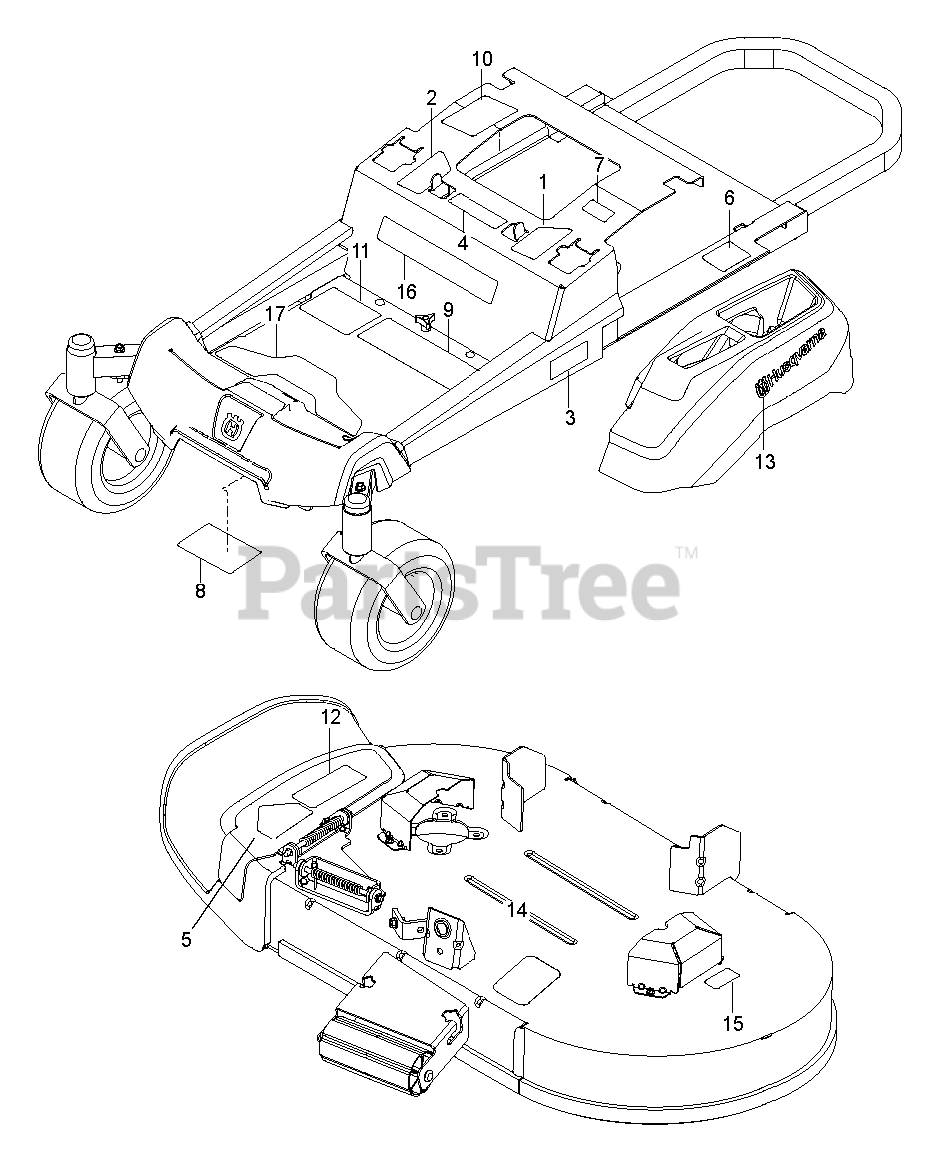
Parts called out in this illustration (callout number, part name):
1	DECAL.ZTR.RZ.THRTL/PRKBRK.V2.L
2	DECAL.ZTR.RZ.THRTL/PRKBRK.V2.R
3	DECAL
4	EURO DECAL-BATTERY WARNIN6
5	DECAL, DECK DEFLECTOR, WARNING
6	DECAL.ZTR.DONOTTOW.EN/FR.2014
6	DECAL, DO NOT TOW
7	DECAL, EXITING MOWER
8	DECAL, SERVICE
9	DECAL ZTR WARNING DECAL DECAL.
10	DECAL.WARNING.CUST.RESP.E85.
11	DECAL.ZTR.STARTINS.READYSTART
12	DECAL.DECK.6MIL./DEF.SHLD.WARN
13	DECAL.HUSQVARNA.210MM
14	DECAL, BELT ROUTING
14	DECAL.BELTROUT.46".ZTR.ENG/FRE
16	DECAL ZTR BRAND GRAPHIC DECAL.
17	PAD.RZ.FOOTREST.PLATE
